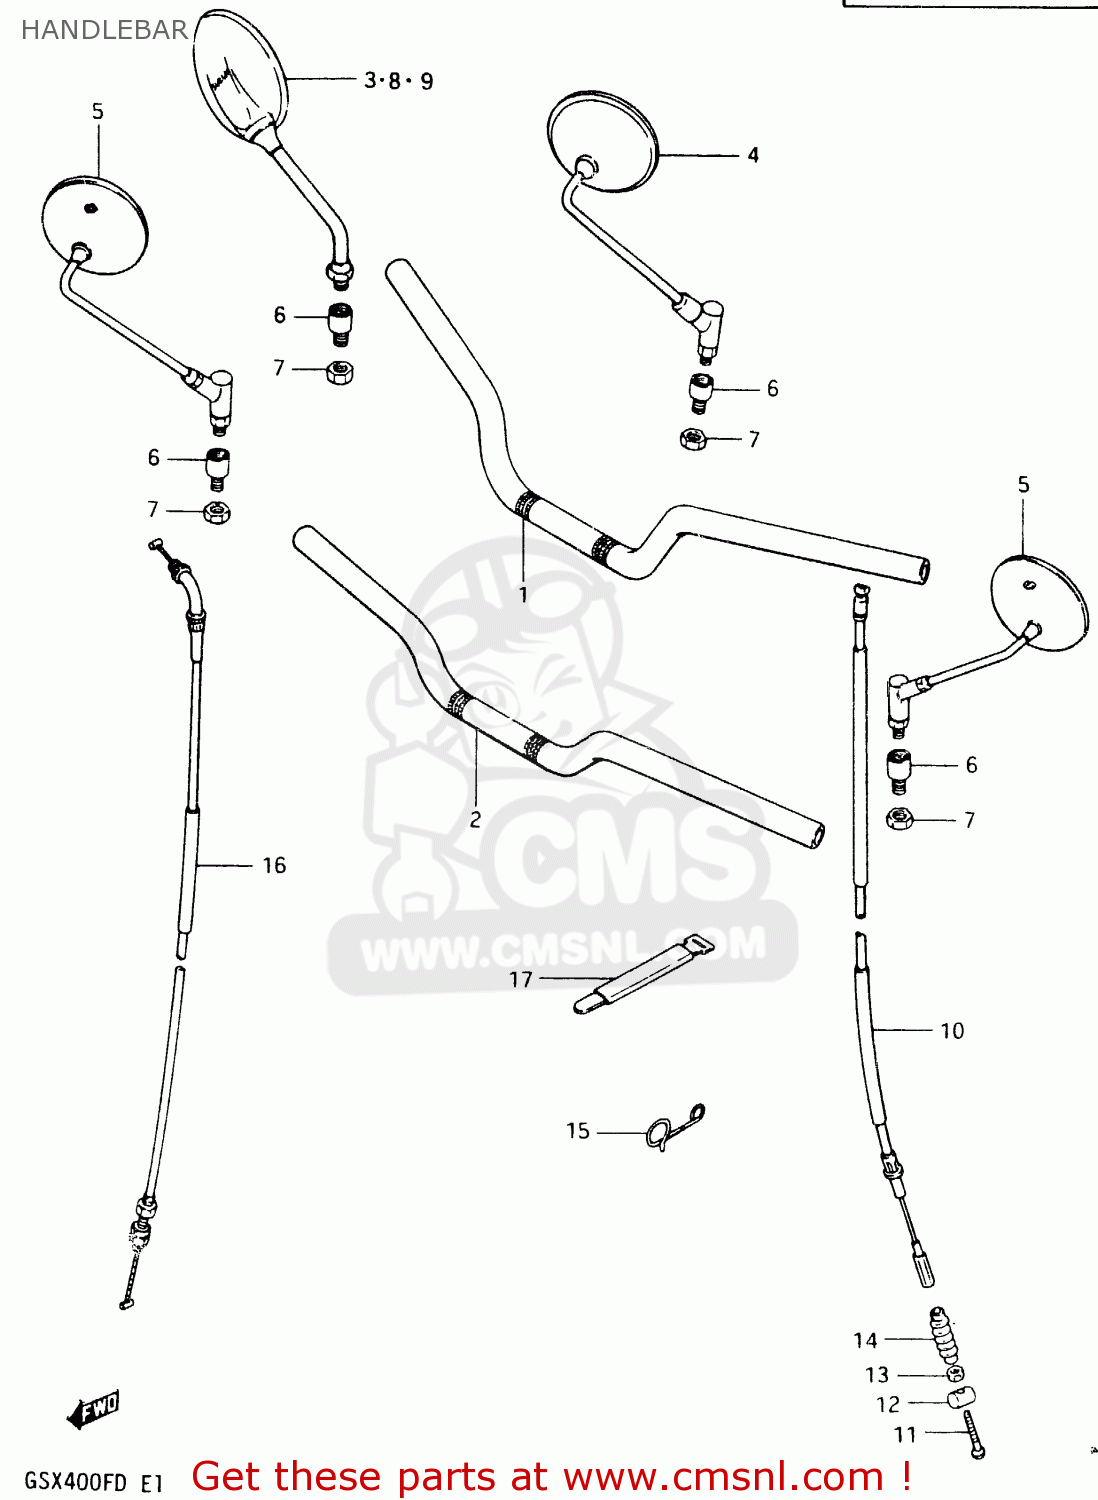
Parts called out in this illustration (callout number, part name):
1	HANDLEBAR (NEUTRAL)
2	HANDLEBAR (FLAT)
3	MIRROR, REAR VIEW
4	MIRROR ASSY,RR VIEW
5	MIRROR ASSY,RH
6	CUSHION,REAR VIEW MIRROR
7	NUT
8	MIRROR, REAR VIEW
9	MIRROR, REAR VIEW
10	CABLE, CLUTCH (FLAT)
11	SCREW
12	PIN
13	NUT
14	DUST SEAL
15	GUIDE,CLUTCH CABLE
16	CABLE ASSY,THR
17	CLAMP
